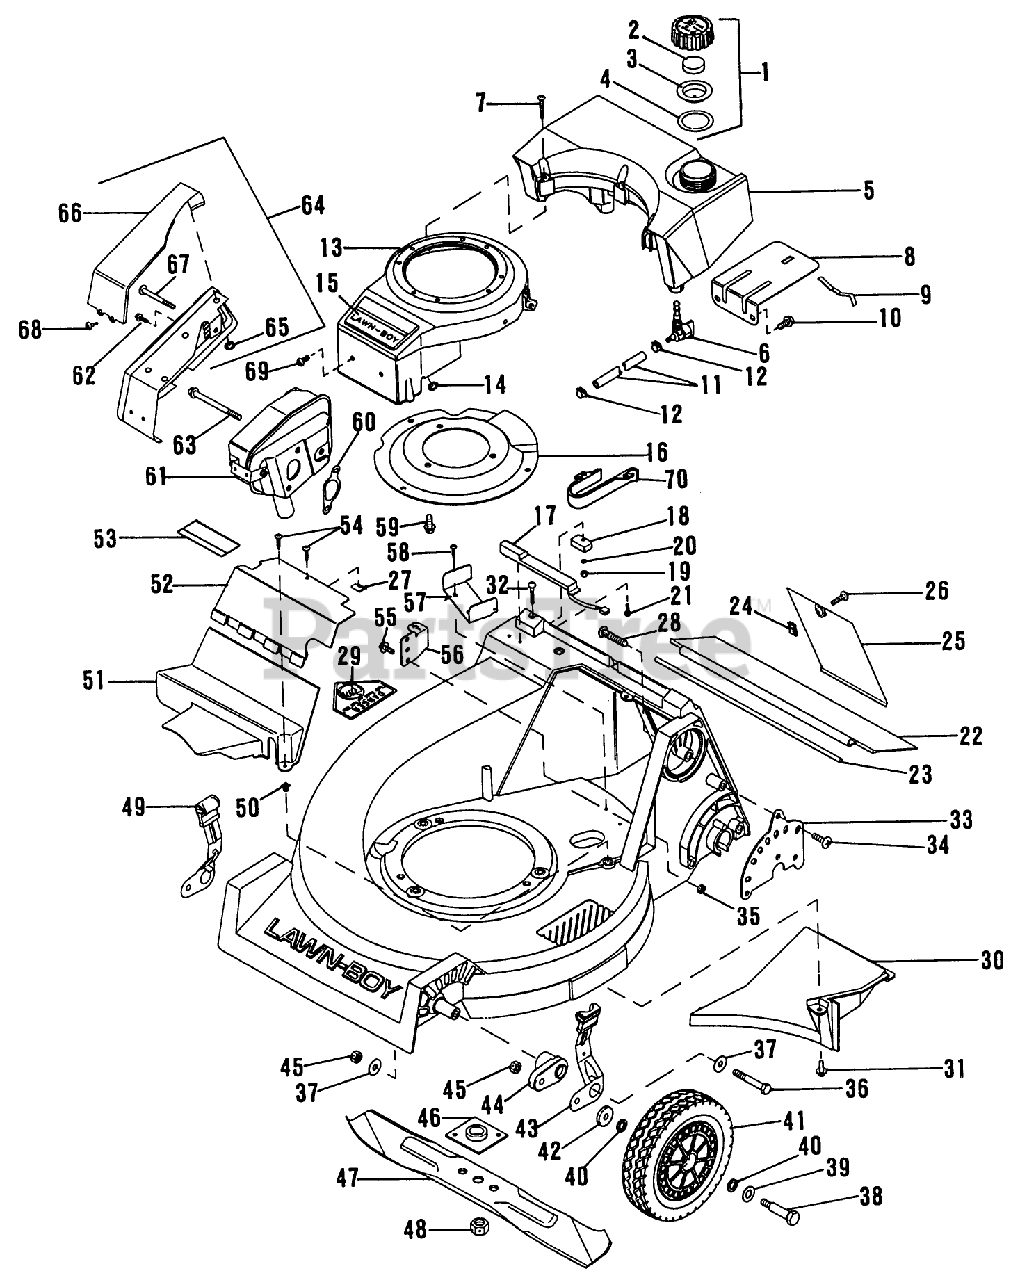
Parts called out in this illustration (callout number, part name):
1	CAP AY - F/OIL SM
2	BAFFLE - FOAM SM
4	GASKET-FUELCAP SM
6	DISC/LB SER.BUL.#6
7	DISC.LB SER.BUL.#6
8	DISC. LB SER.BUL.#6
9	SPRING
11	GAS LINE SM
12	HOSE CLAMP SM
14	NUT-PUSH
16	PLATE SM
17	SWITCH AY DELTA
24	SPEED NUT LARSON
25	DOOR-ACCESS ELECT.
26	SCREW-CROSS RECESS
27	NUT-SPEED
30	CHUTE BAFFLE NYL
33	PLATE HGT CMS
34	SCREW-BHTF
35	LOCKNUT E
37	WASHER-PLAIN
39	SPACER
40	WASHER
41	WHEEL&TIRE 8" TRI
42	WASHER
43	KNOB & SPRING CMS
45	NUT-JAM, LOCKING
46	PLATE AND COLLAR ASM
48	NUT-BLADE
49	KNOB & SPRING CMS
50	NUT-CLIP
54	SCREW S
60	GASKET - EXH SM
62	SCREW S
63	SCREW-SEMS
64	MUFFLER GUARD AY
65	NUT-PUSH
66	COVER MUFFLER CP
67	SCREW SM
68	SCREW SM
